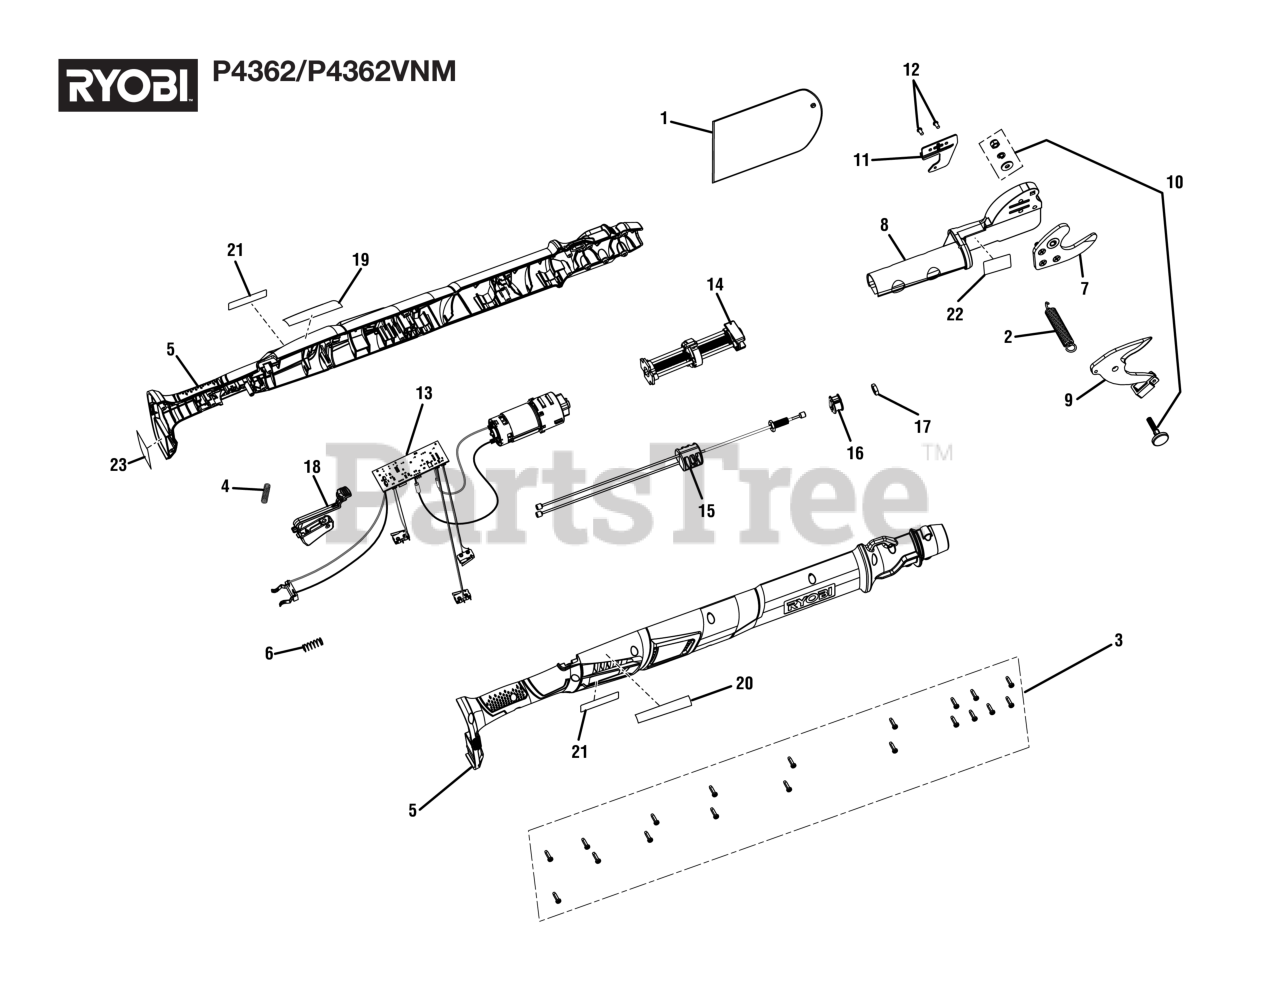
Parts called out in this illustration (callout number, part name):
1	Blade Cover
3	Screw (M4 x 14 mm, T15 Torx Pan Hd.))
5	Handle Assembly
6	Compression Spring
7	Bottom Blade Assembly
8	Cutting Head Assembly
9	Cutting Blade Assembly
10	Bolt Assembly
11	Cutting Head Hook
12	Screw (M4 x 8 mm, Pan Hd.)
13	Gear Box, Motor, and Motor Controller Assembly
14	Power Screw Assembly
15	Cable Assembly
16	Rubber Seal
17	Hex Nut (M8)
18	Trigger and Saftey Button Assembly
19	Icons/Warning Label
20	Data/Warning Label
21	Logo Label
22	Instruction/No Hands Label
23	QR Code Label
